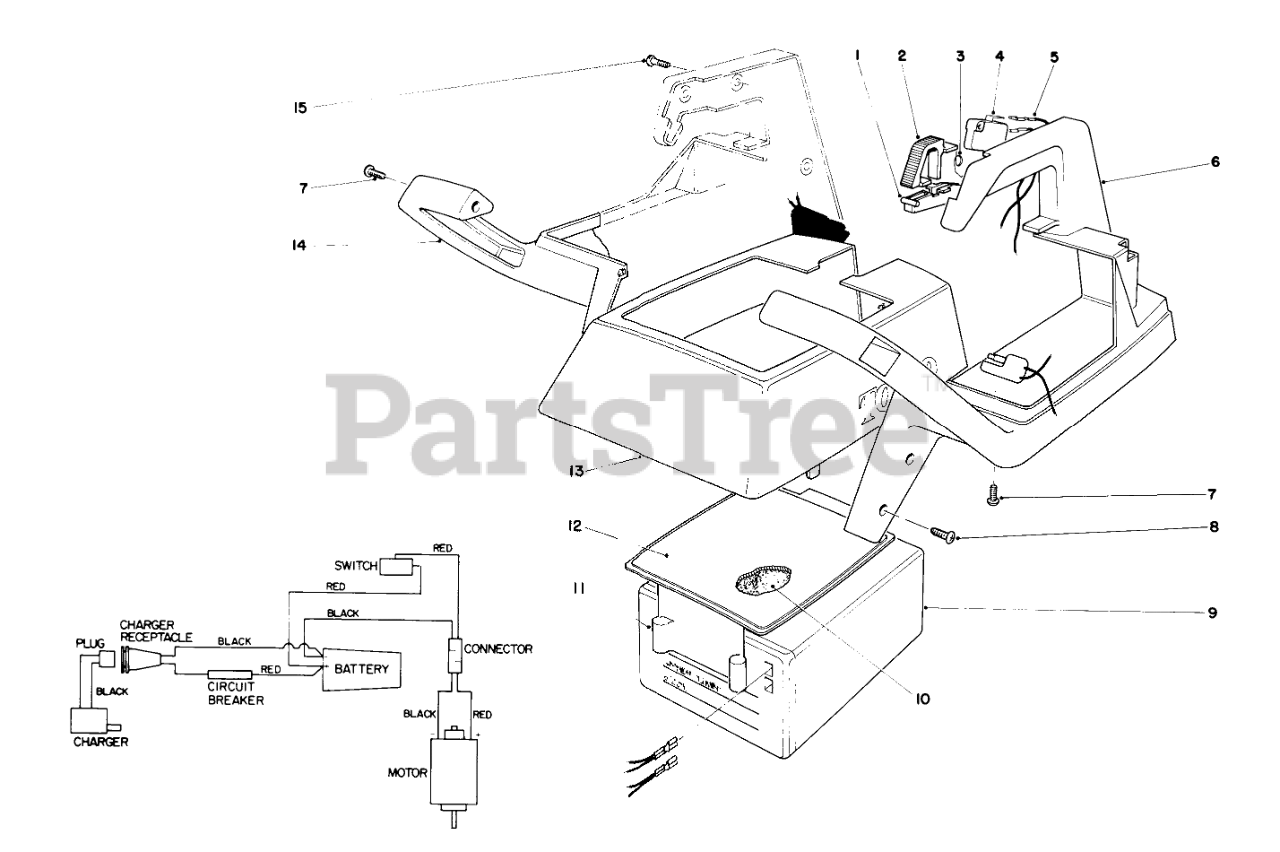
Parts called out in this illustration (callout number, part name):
1	TRIGGER
2	TRIGGER LOCK
3	SPRING
4	Switch
5	Wiring Harness
6	LH BATTERY CASE/HNDL
7	Screw
8	10-16 X .31 SCREW
9	BATTERY
10	FOAM PAD
11	CONTROL PANEL, CL-710
12	DECAL, FRONT PANEL, CSA
13	Cover
14	RH BATTERY CASE/HNDL
15	SCREW-PPH
